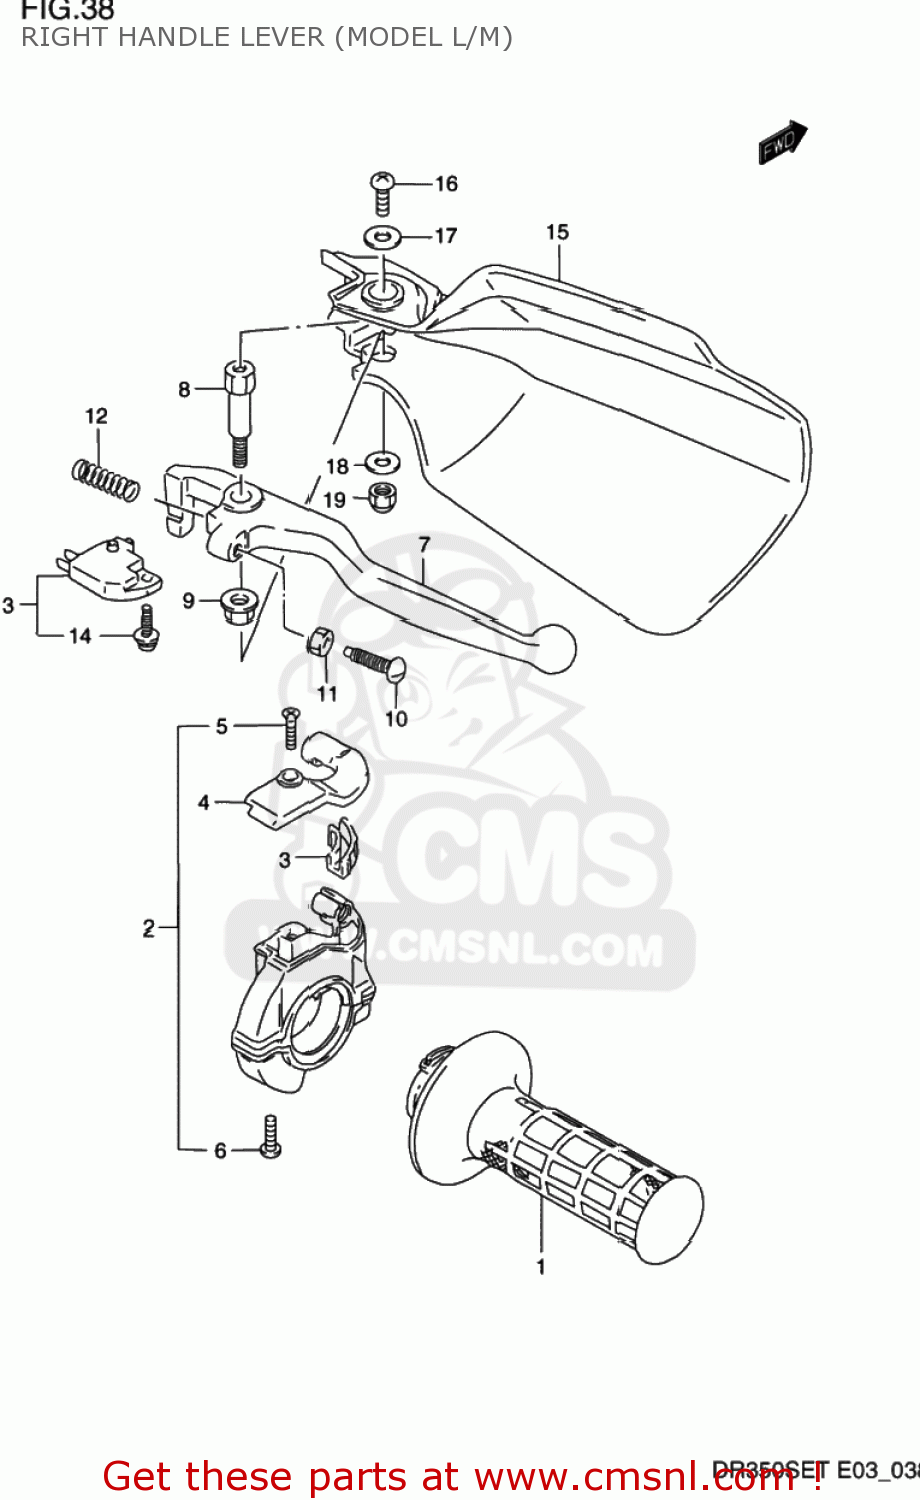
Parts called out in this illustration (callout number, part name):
1	GRIP,THROTTLE
2	CASE ASSEMBLY,THROTTLE
3	GUIDE PIECE,THROTTLE
4	COVER,THROTTLE CASE
5	SCREW 4X10
6	SCREW
7	LEVER,BRAKE
8	BOLT,BRAKE LEVER PIVOT
9	NUT 6MM
10	BOLT,ADJUST
11	NUT ,5MM
12	SPRING,RETURN
13	SWITCH ASSEMBLY,STOP
14	SCREW
15	COVER,KNUCKLE,R
16	SCREW(5X10)
17	WASHER (5.5X16X1.2)
18	WASHER (6.5X17X1.6)
19	NUT 6MM
